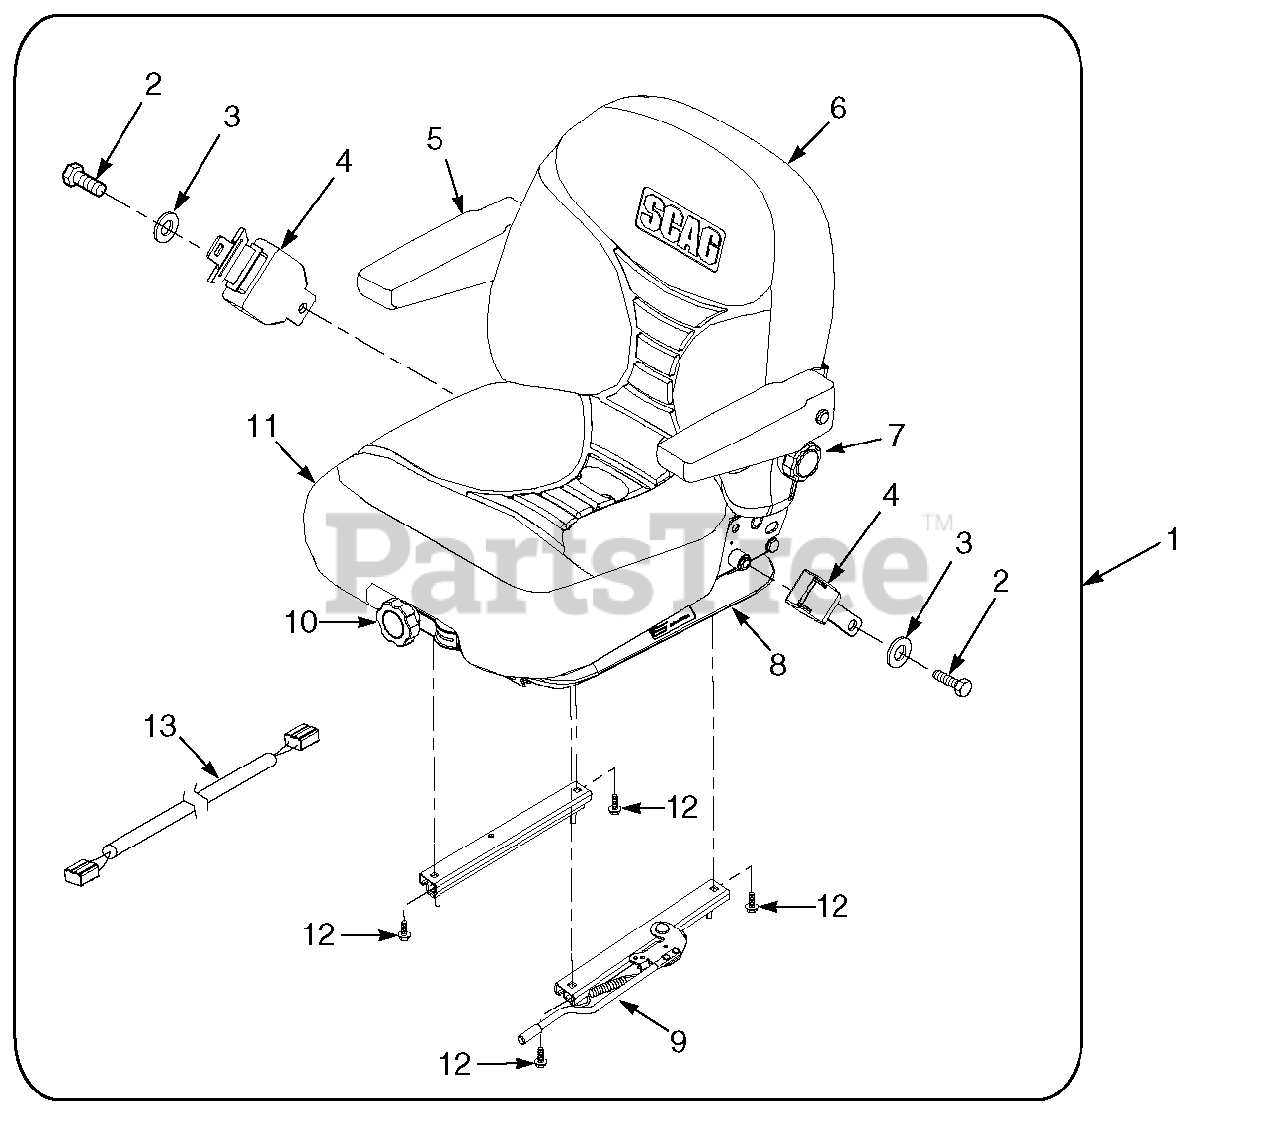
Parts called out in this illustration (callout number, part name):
1	Suspension Seat Assembly w/seat belt
2	Bolt, Hex Head 7/16-20 x 1"
3	Flatwasher, 7/16-.500 x 1.25 x .083
4	Retractable Seat Belt
5	Armrest Only
6	Back Cushion Kit
7	Lumbar Kit
8	Shock Absorber Kit
9	Seat Adjustment, Track Set
10	Weight Adjustment Kit
11	Seat Cushion Kit Seat Drain Kit
12	Bolt, Hex Head 5/16-18 x 1-3/4"
13	Wire Harness Adapter
